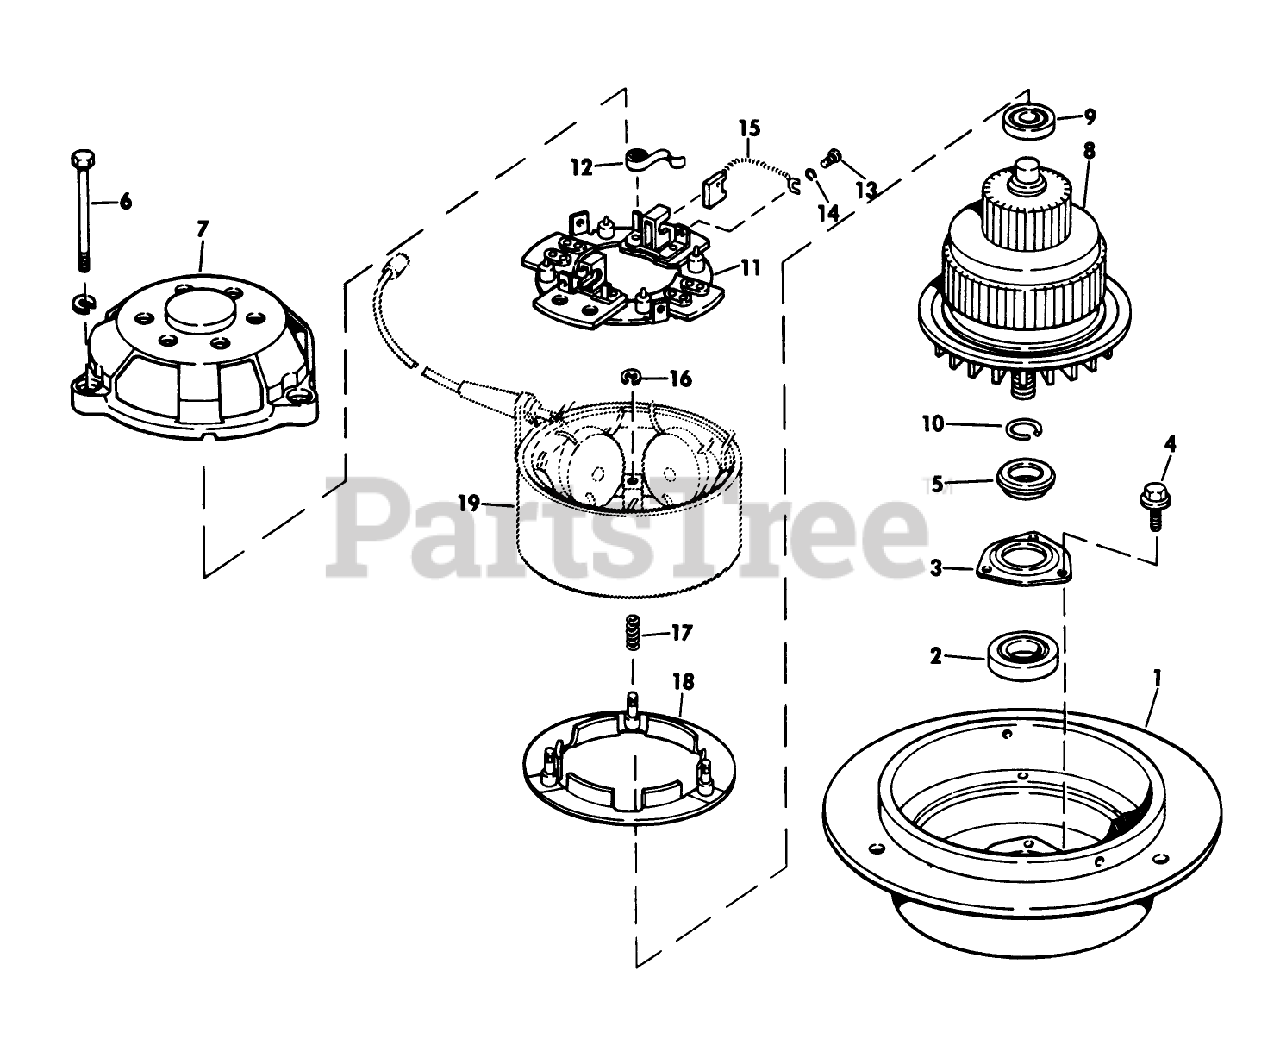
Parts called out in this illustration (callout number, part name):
1	End Bell-Motor
6	Screw-Motor Assembly
15	Brush
18	Brake Disc
19	Stator Assembly
